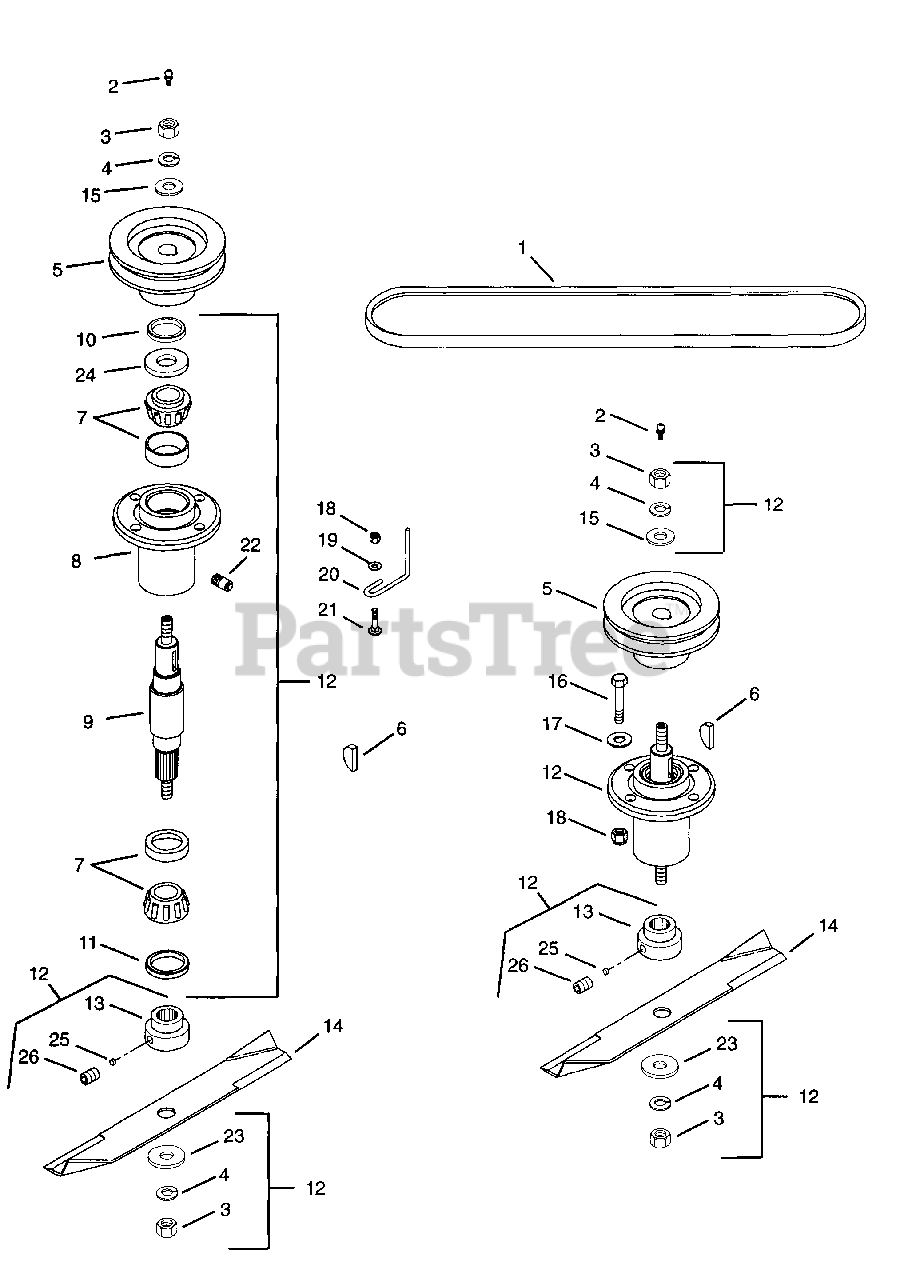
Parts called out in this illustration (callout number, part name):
1	V-Belt A-Section
2	Fitting-Lube
3	Nut-Locking-Center .62-11
3	Nut-Hex .62-11
4	Washer-Lock .62 x .156
6	Key-Woodruff .25 x 1.00
7	Bearing, Cone w/Grease
8	Bearing Housing
9	Spindle Shaft
10	Seal 1.987 x 1.500 x .313
11	Seal 1.987 x 1.375 x .313
12	Service Kit Assembly
14	Blade - 36" Mower
15	Washer-Flat-Steel .687 x 1.312 x .150
16	Bolt-Hex .38-16 x 1.50 Grade 5
16	Bolt-Hex .36-16 x 1.25 Grade 5
17	Washer-Flat-Steel .281 x .62 x .065
17	Washer-Flat-Steel .438 x 1.00 x .083
18	Nut-Locking-Nylon .38-16
18	Nut-Locking-Center .38-16
19	Washer-Flat-Steel .406 x .812 x .065
19	Washer-Flat-Steel .406 x 1.00 x .188
20	Belt Brake Finger 2-Deck Clutch
21	Bolt-Round Head Square Neck .38-16 x 1.25 Grade 5
22	Relief Fitting-Grease
23	Washer-Flat-Steel .640 x 1.81 x .250
24	Washer-Hardened-Thrust 1.007 x 1.542 x 062
26	Screw-Set .25-20 x .25
